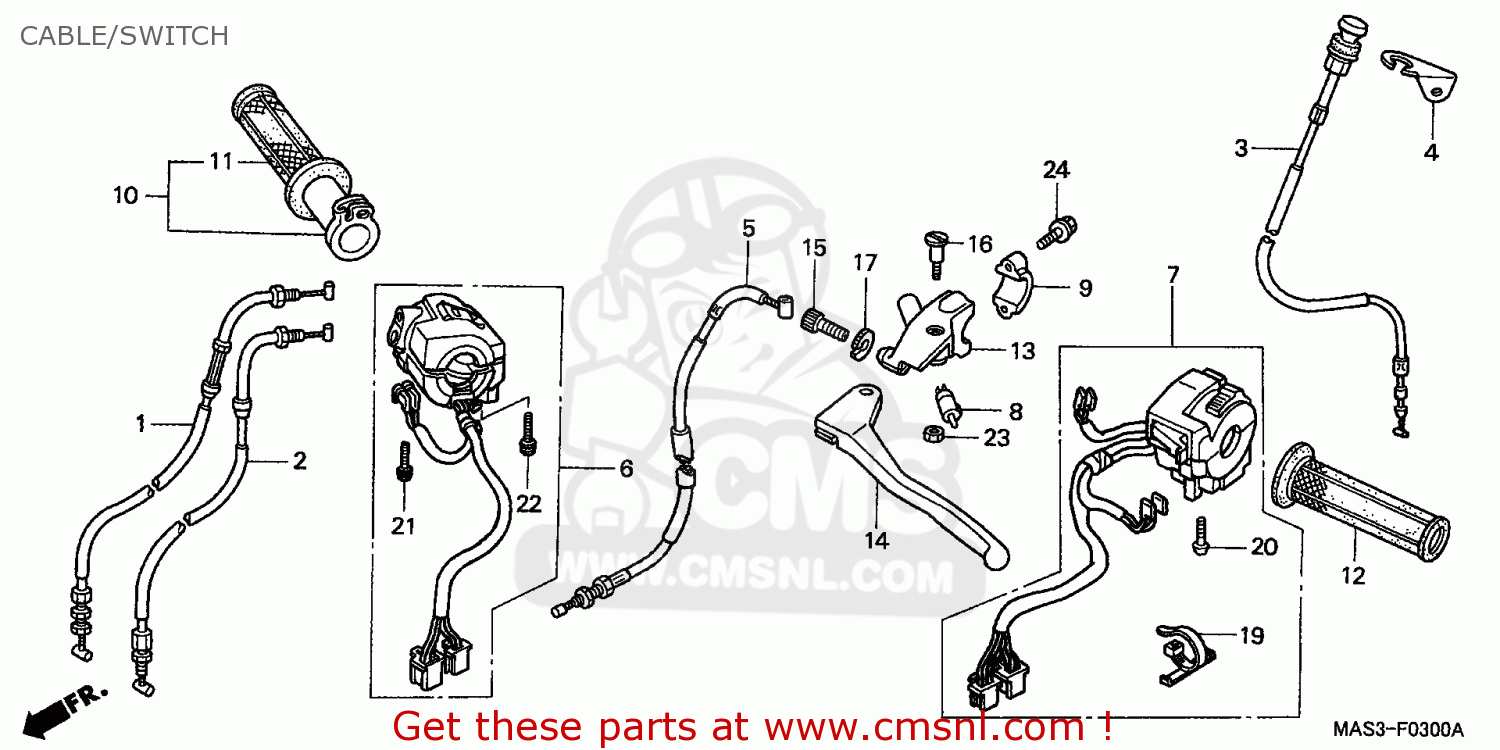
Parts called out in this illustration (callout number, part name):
1	CABLE COMP,A THRO
2	CABLE COMP B,THRO
3	CABLE COMP,CHOKE
4	STAY,CHOKE CABLE
5	CABLE COMP.CLUTCH
6	SET,SW ASSY.ST KI
7	SET,SW ASSY.WINKE
8	SWITCH,FR.LEVER
9	HOLD,MAS.CYLINDER
10	GRIP COMP.,R.
11	GRIP,R.HANDLE
12	GRIP,L.HANDLE
13	BRKT.,HNDL.LEVER
14	LEVER COMP.,L.HAN
15	BOLT
16	BOLT,LEVER PIVOT
17	NUT,FIXING
19	BAND HARNESS
20	SCREW,PAN,5X20
21	SCREW WASHER 5X20
22	SCREW-WASHER,5X25
23	NUT,HEX 6MM
24	BOLT,FLANGE,6X22
